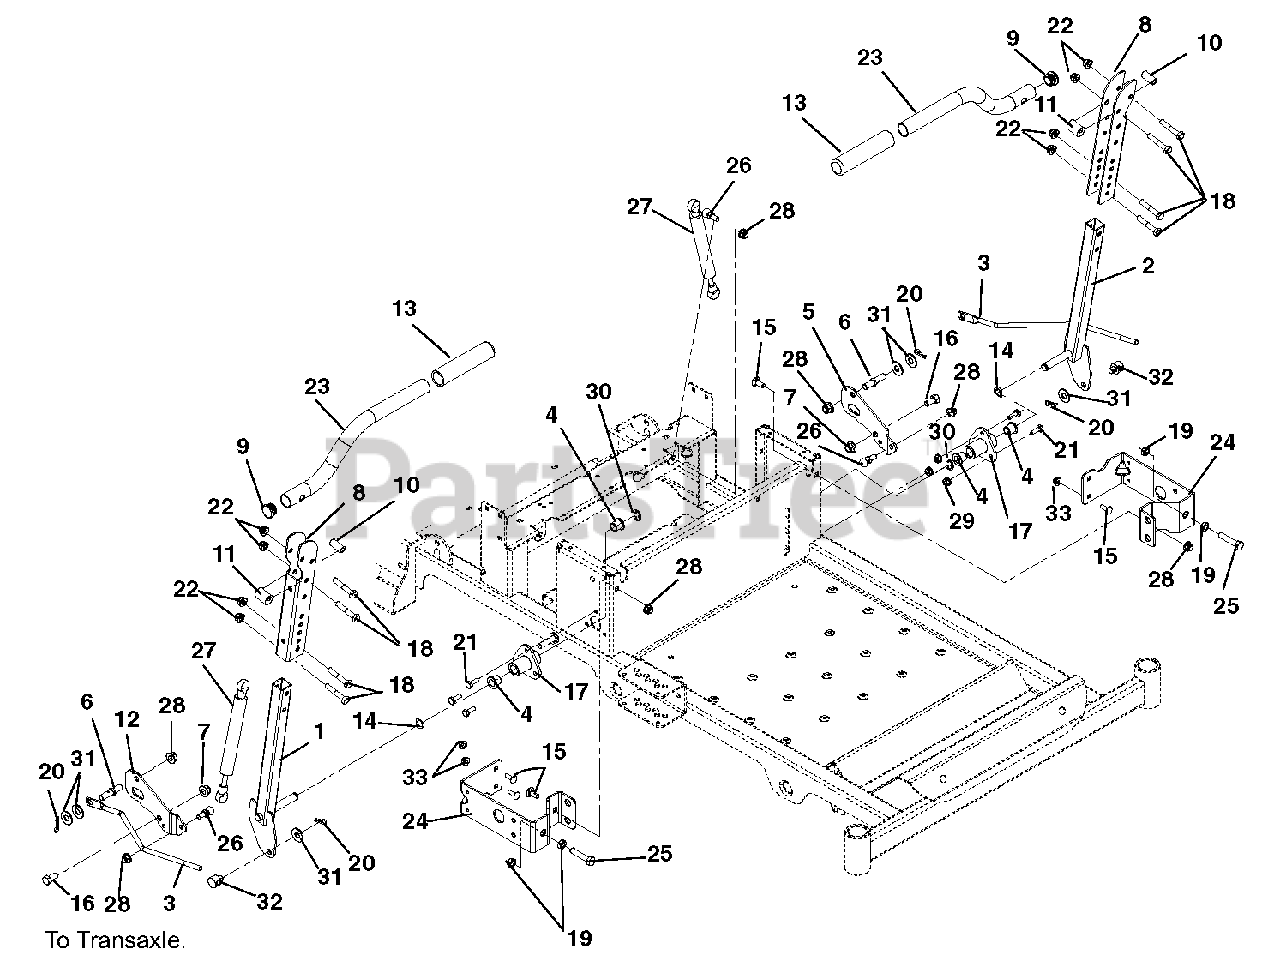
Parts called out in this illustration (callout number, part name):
1	Weldment, RH Control Arm
2	Weldment, LH Control Arm
3	Link, Steering
4	Bushing, Flanged .500 x .625
5	Plate, Damper LH
6	Pin, Trans
7	Nut, .38-16 Nyloc Flange
8	Channel, Upper Handlebar
9	Caplug, Handlebar
11	Eccentric
12	Plate, Damper RH
13	Grip, Handlebar
14	Washer, Wave .50 x .75 x .015 .13 FRHT
15	Bolt, Round Head Square Neck .31-18 x .75
16	Bolt, Hex .38-16 x .75 Grade 5
17	Bushing, Flanged
18	Bolt, Hex .31-18 x 1.75 Grade 5
19	Nut, Hex Jam .375-16
20	Pin, Hair Internal .08 x .18 x 1.18
21	Bolt, Hex .25-20 x .75 Grade 5
22	Nut, .31-18 Nyloc Flange
23	Handle, Steering
24	Bracket, Speed Adjustment/Seat Pivot
25	Bolt, Hex .375-16 x 1.750 Full Thread
26	Stud, Ball
27	Damper
28	Nut, Flange .31-18
29	Nut, Locking-Top-Flange .25-20
30	Ring, Retaining External .500 x .042
31	Washer, Flat Steel .438 x 1.00 x .083
32	Trunnion, Brake .31-18
33	Nut, .25-20 Nyloc Flange
